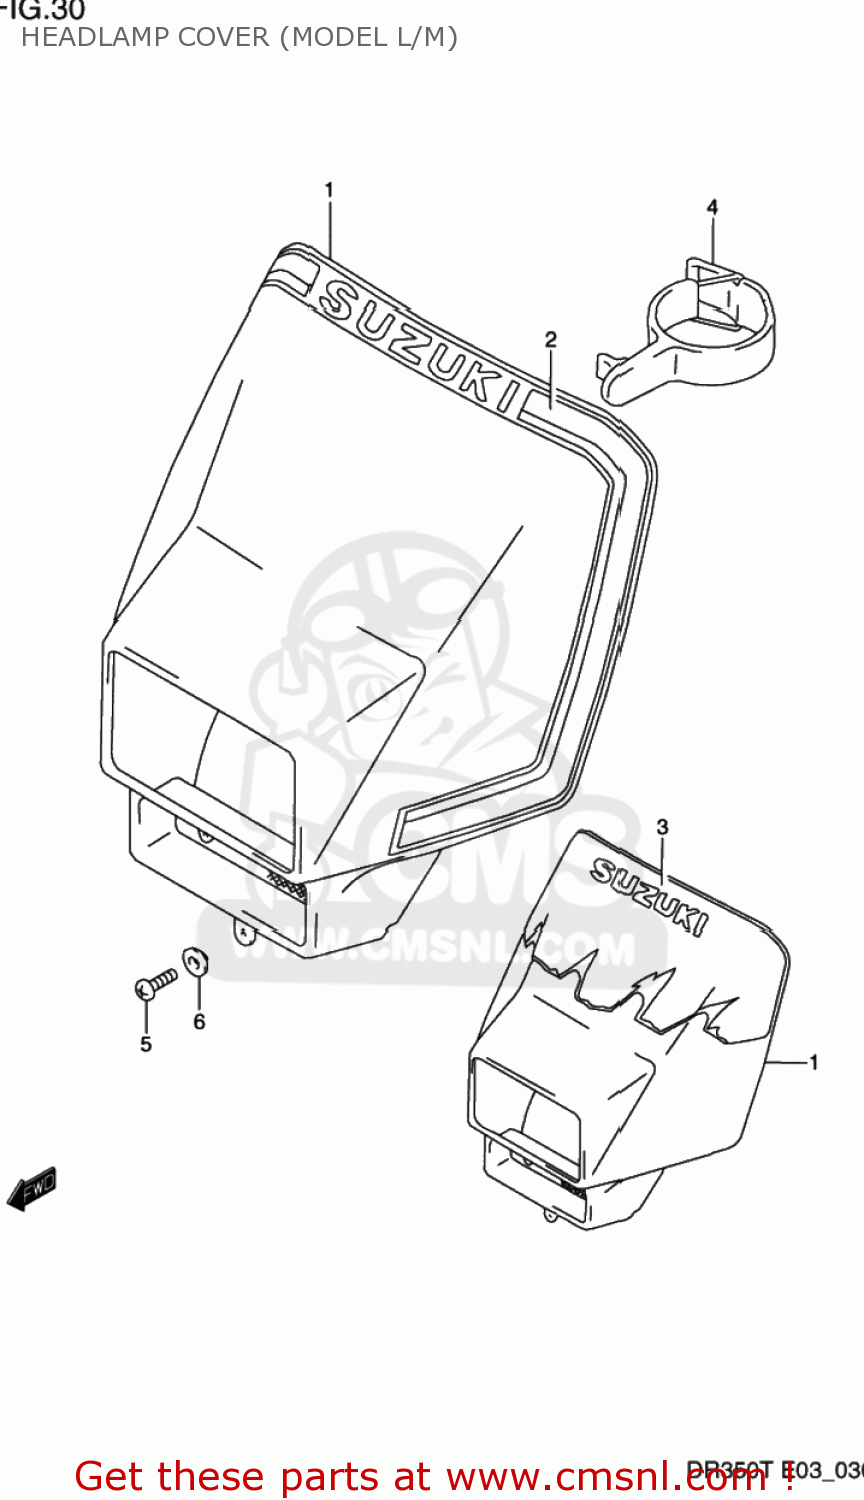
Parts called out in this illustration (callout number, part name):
1	COVER,HEADLAMP
2	TAPE,HEADLAMP COVER
3	TAPE,HEADLAMP COVER
4	BAND,HEADLAMP COVER
5	SCREW(5X12)
6	WASHER
